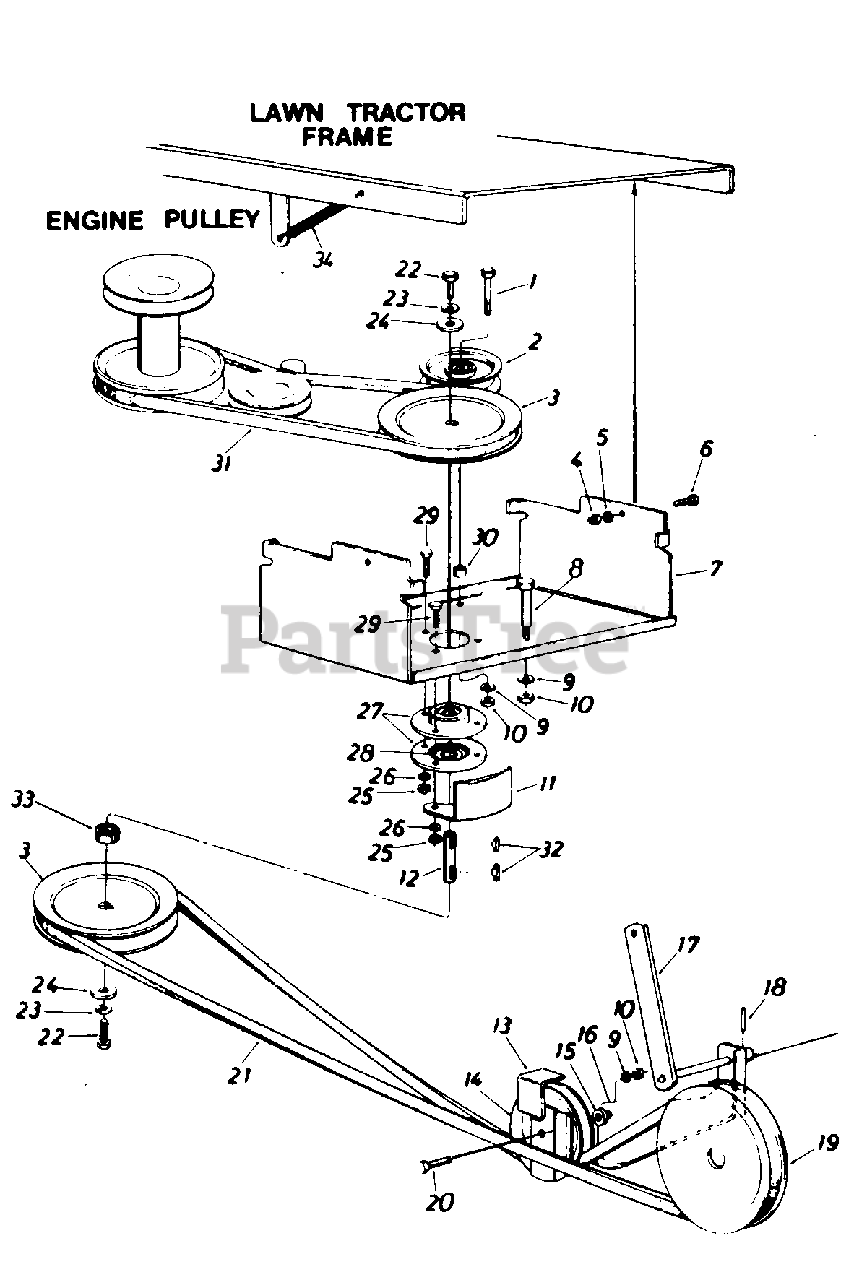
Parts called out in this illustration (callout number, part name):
1	Hex Bolt 3/8-16 x 2.00" Lg.
2	Fl.-Idler w/Flanges 3-3/4" O.D.
3	5/8" "V"-Pulley .790" I.D. x .650" O.D.
4	Hex Nut 3/8-24 Thd.
5	L.-Wash. 3/8" I.D. Heavy Duty
6	Hex Bolt 3/8-24 x .88" Lg.
9	L.-Wash. 3/8" I.D.
10	Hex Nut 3/8-16 Thd.
13	Belt Separator Plate
14	Fl.-Idler w/Flanes 3.25"
15	Fl.-Wash. .406" I.D. x 1.25"
18	Spring Pin Roll 3/16" Dia.
19	5/8" V-pulley 1.50" I.D. x 6.50" O.D.
20	Hex Bolt 3/8-16 x 1.75" Lg.
21	"V" -Belt
22	Hex Bolt 5/16-18 x .88" Lg. Spec
23	L.-Wssh 5/16" I.D.
24	Fl.-Wash. .344" I.D. x 1.125"
25	Hex Nut 5/16-18 Thd.
26	L.-Wash. 5/16" I.D.
27	Bearing Housing 1.85" I.D.
28	Ball Bearing 1.85" O.D.
29	Hex Sems Bolt 5/16-18 x .75"
30	Spacer
31	Belt 1/2" Wide x 52" Long
32	Hi-Pro Key 3/16" x 5/8"
33	Spacer.66" I.D. x 1.0" O.D.
34	Extension Spring
